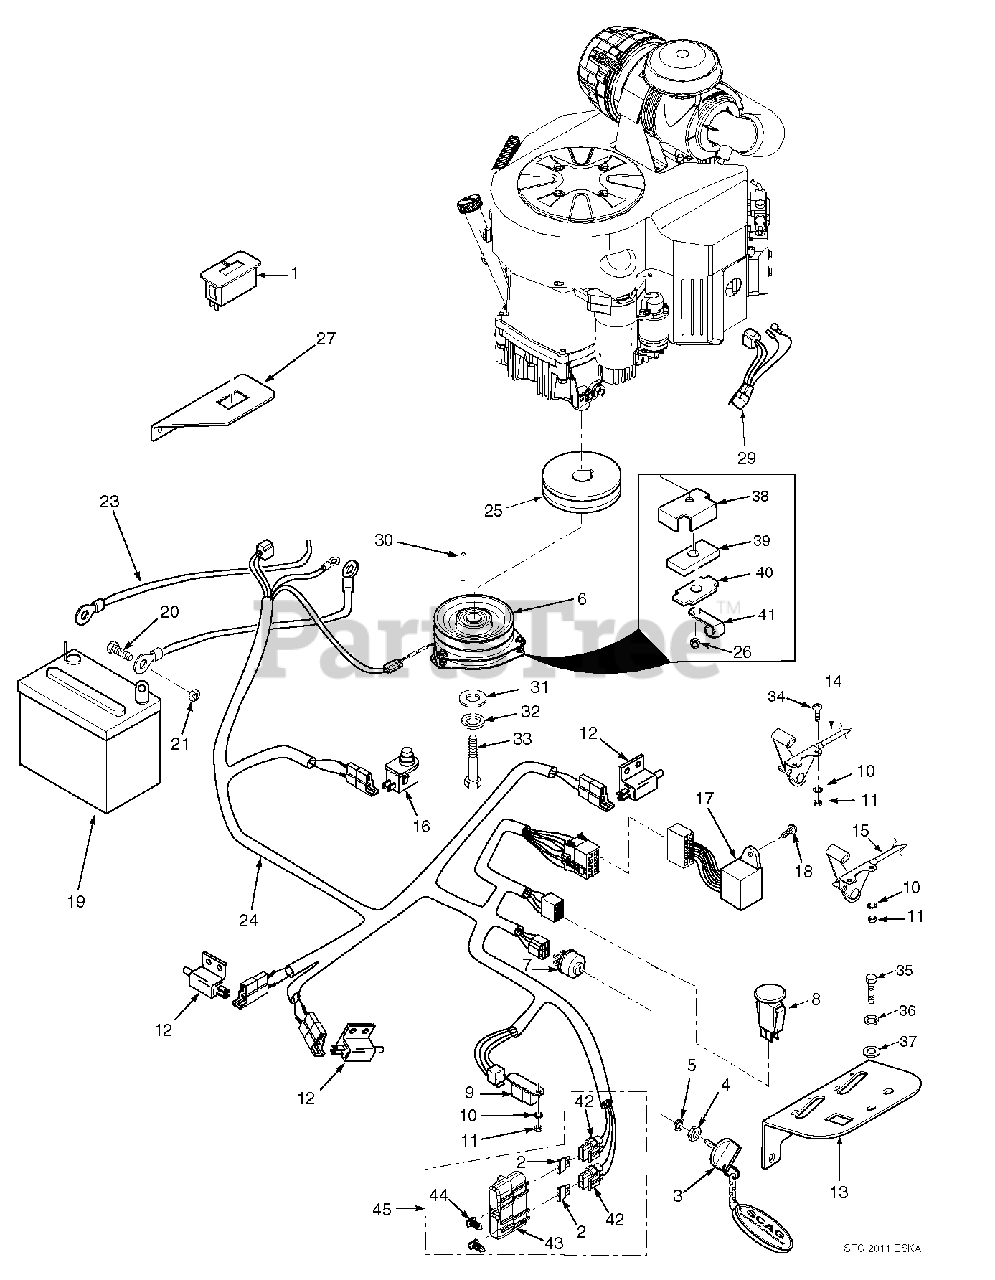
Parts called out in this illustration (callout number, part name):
1	Hourmeter
2	Fuse, 20 amp
3	Key, Ignition
3	Key Assembly w/Fob
4	Nut, Hex 5/8-32
5	Lockwasher, 5/8" Internal
6	Electric PTO Clutch GT3.5
7	Switch, Ignition
8	Switch, PTO
9	Relay
10	Lockwasher, #10 External Tooth
11	Nut, Hex #10-32
12	Switch, N/O
13	Panel, Instrument
14	Choke & Throttle Control
14	Choke Control
15	Throttle Control
16	Switch, Seat
17	Module, Interlock
18	Screw, #10-32 x .5" Phillips Head
19	Battery, 350CCA
20	Bolt, Hex Head 1/4-20 x .5"
21	Nut, Hex 1/4-20
22	Cable, Battery Black
23	Cable, Battery Red
24	Wiring Harness, Main
24	Wire Harness, Main
25	Pulley, 5.45 OD x 1.125" Bore
26	Nut, Elastic Stop 5/16-18 Key
27	Mounting Bracket, Hour Meter
28	Screw, #10-32 x 1.5" Phillips Head
29	Adapter, Wiring Harness
30	Key, 1/4 x 1/4 x 3-1/4"
31	Flatwasher, 7/16-.469 x 1-3/4" x 1/4"
32	Lockwasher, 7/16"
33	Bolt, Hex Head 7/16-20 x 2-1/2" UNF
34	Screw, #10-32 x 3/4"
35	Bolt, Hex Head 5/16-18 x 3/4"
36	Lockwasher, 5/16"
37	Flatwasher, 5/16-.375 x .875 x .083
38	Backing Plate
39	Rubber Pad, Clutch Stop
40	Plate, Backing
42	Fuse Holder
43	Cover, Sealed Double
